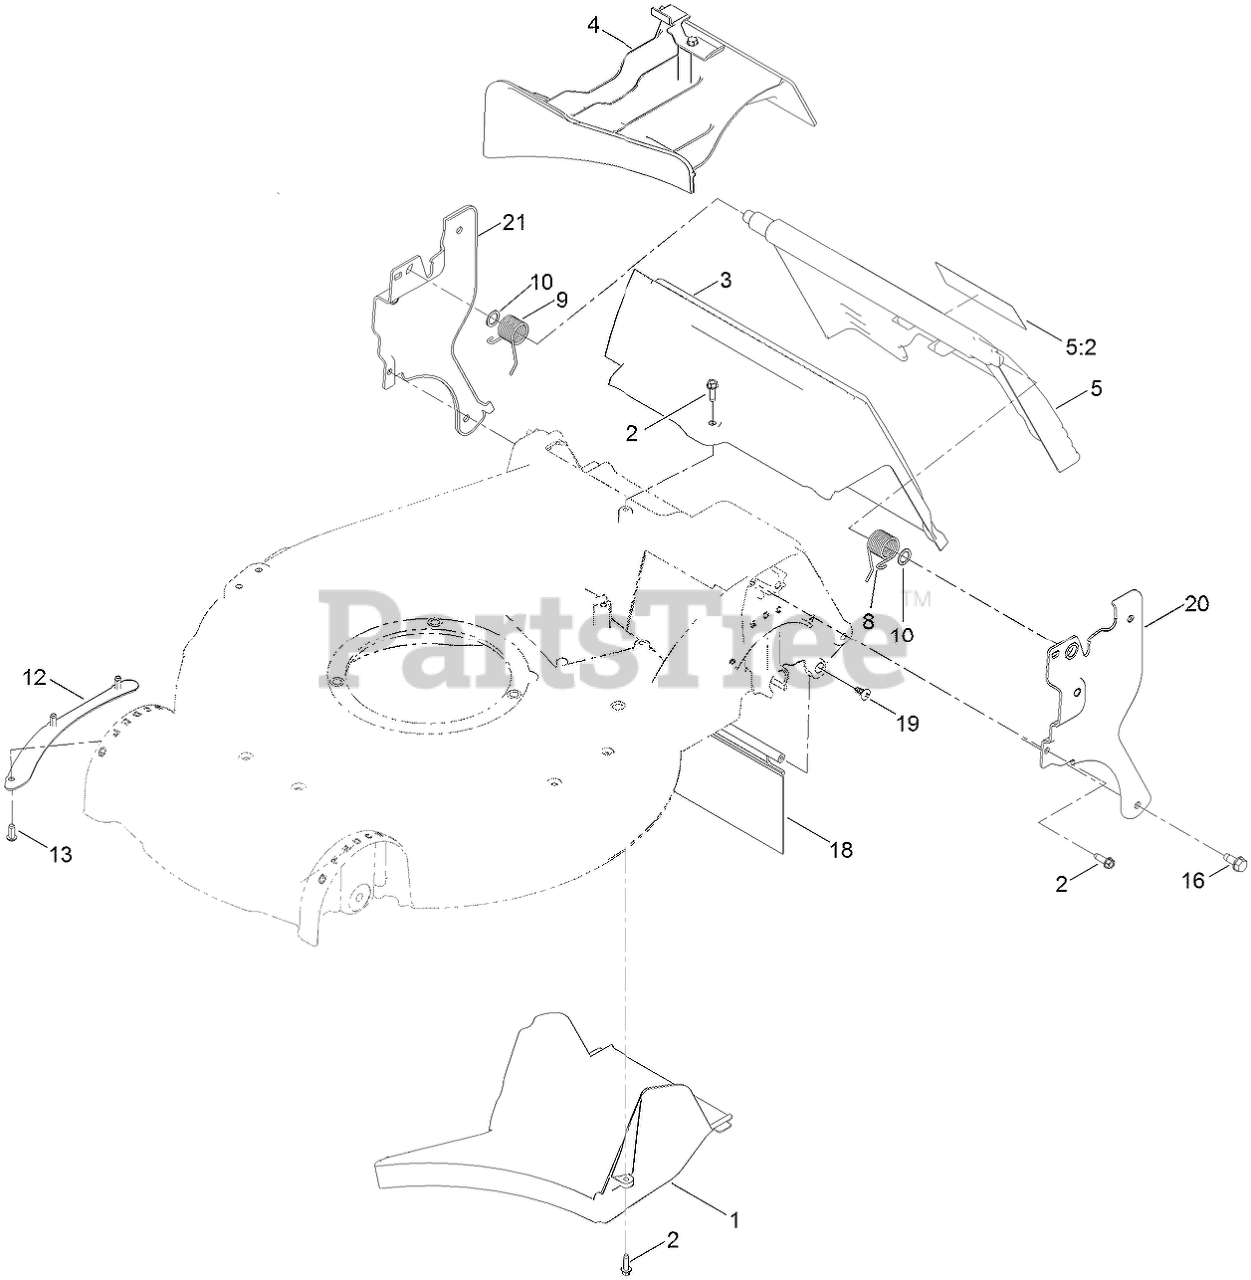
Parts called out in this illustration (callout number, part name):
1	TUNNEL-DISCHARGE
2	SCREW-HWHTF
4	MULCH PLUG ASM
5	REAR DOOR ASM
5:2	DECAL-WARNING
8	SPRING-TORSION
9	SPRING-TORSION
10	WASHER-NYLON
12	SHEET-LIP
13	SCREW
16	SCREW-THD ROLL, HWH
18	SHIELD-TRAILING
19	SCREW-PTH
20	PLATE-HANDLE, LH
21	PLATE-HANDLE, RH
